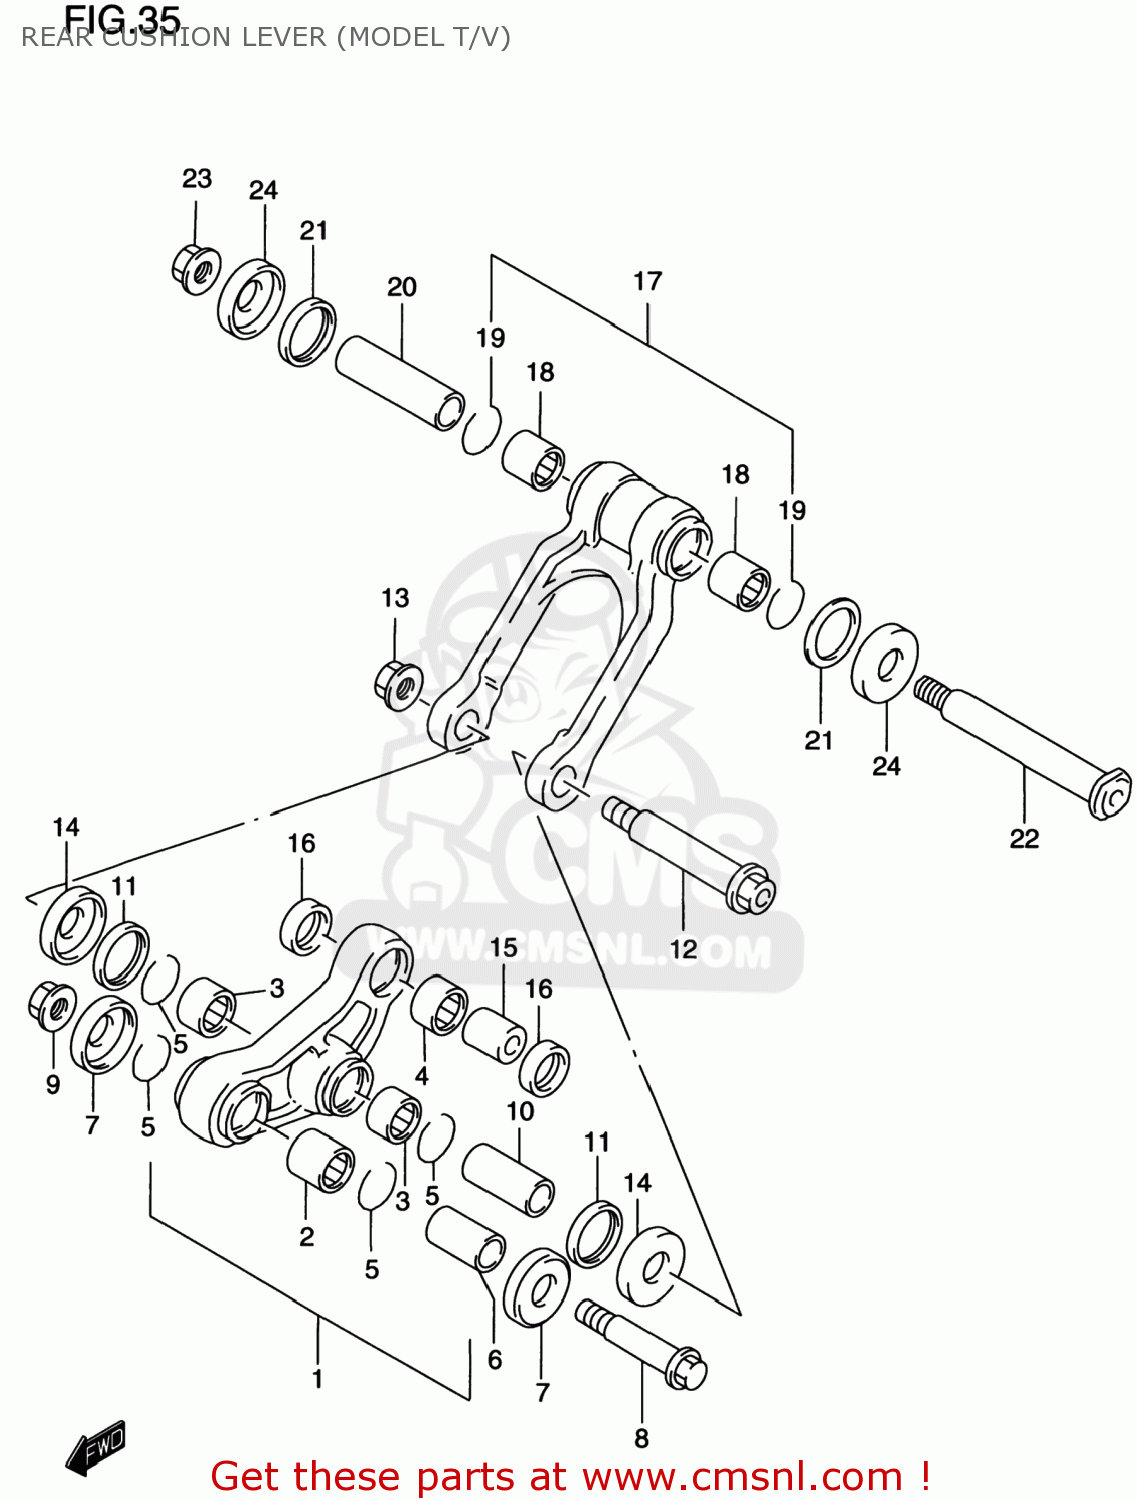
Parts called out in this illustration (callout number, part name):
1	LEVER SET,RR CUSHION
2	BEARING(20X27X25)
3	BEARING(22X28X20)
4	BEARING(20X26X12)
5	CIRCLIP
6	SPACER,RR CUSHION LEVER FR
7	SEAL,RR CUSHION LEVER FR DUST
8	BOLT,RR CUSHION LEVER FR
9	NUT 12MM
10	SPACER,RR CUSHION LEVER CTR
11	SEAL,RR CUSHION LEVER CTR
12	BOLT,RR CUSHION LEVER CTR
13	NUT
14	CAP,RR CUSHION LEVER CTR
15	SPACER,RR CUSHION LEVER RR
16	SEAL,OIL(20X26X4.5)
17	ROD SET,RR CUSHION LEVER
18	BEARING(22X28X20)
19	CIRCLIP
20	SPACER,RR CUSHION ROD
21	SEAL,RR CUSHION LEVER CTR
22	BOLT,RR CUSHION ROD
23	NUT
24	CAP,RR CUSHION LEVER CTR
